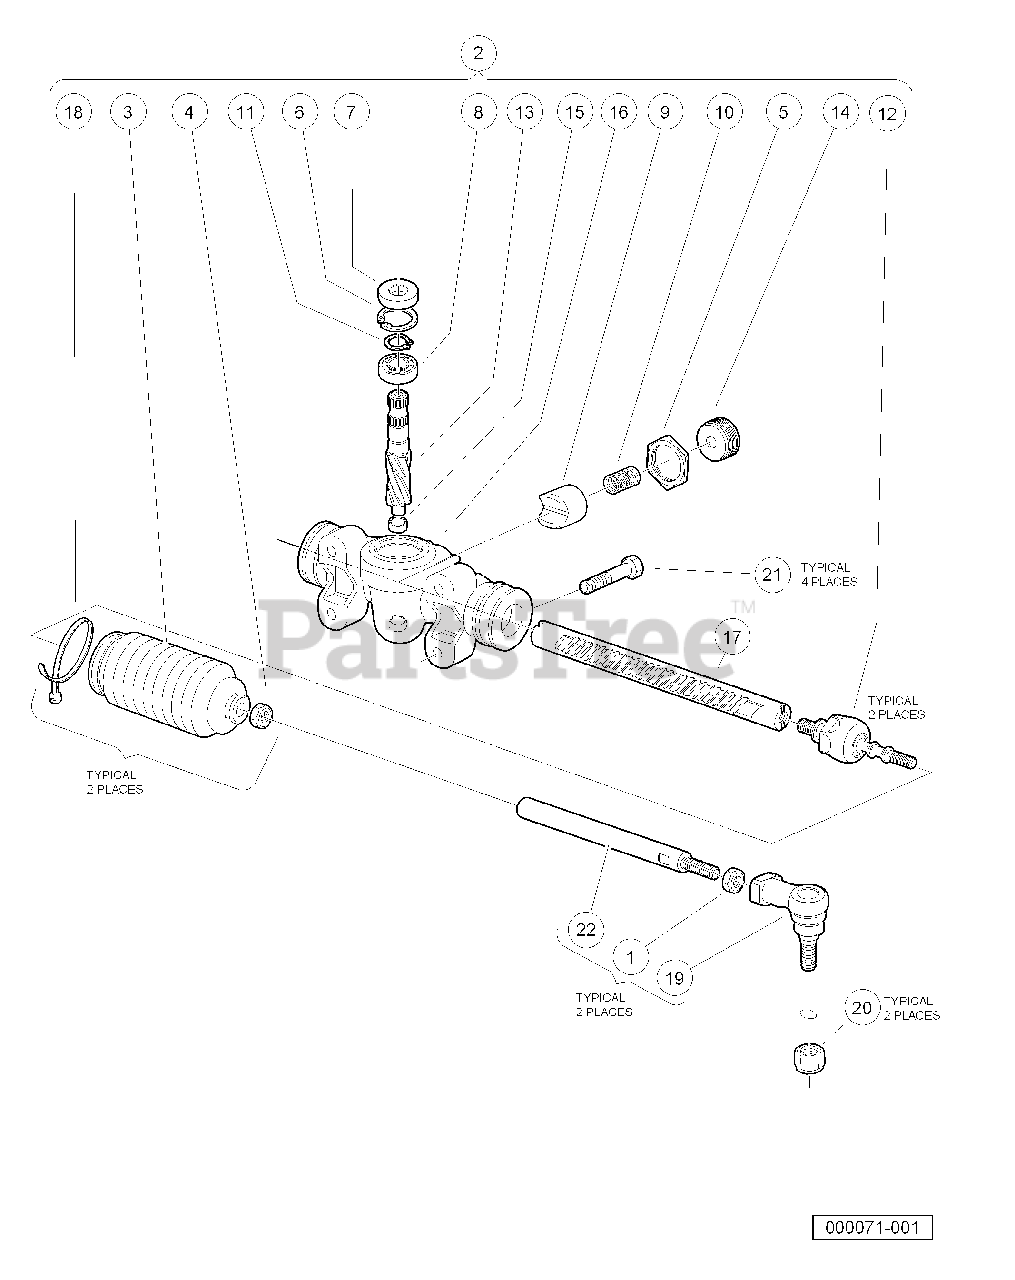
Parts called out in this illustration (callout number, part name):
1	Nut, 12mm Hgx
2	Steering Rack
3	Bellows, Long
4	Nut, 12mm Hex
5	Rack Screw Locknut
7	Seal, Steering Pinion Dust
8	Bearing, Ball
9	Support Yoke
10	Rack Guide Pressure Spring
11	Ring, Stop, C-Type
12	Inner Ball Joint Asm
13	Pinion, Steering
14	Bearing, Lower Pinion
15	Screw, Rack Guide
16	Housing, Steering Gear
17	Rack, Steering
18	Tie Wrap, 8" Nylon
19	End, Tie Rod M12 X 1.25
20	Locknut, M12-1.25 Nylon
21	Bolt, Flange Head, M10x 1.5 X 40 with Loctite
22	Link, Drag, Wt
